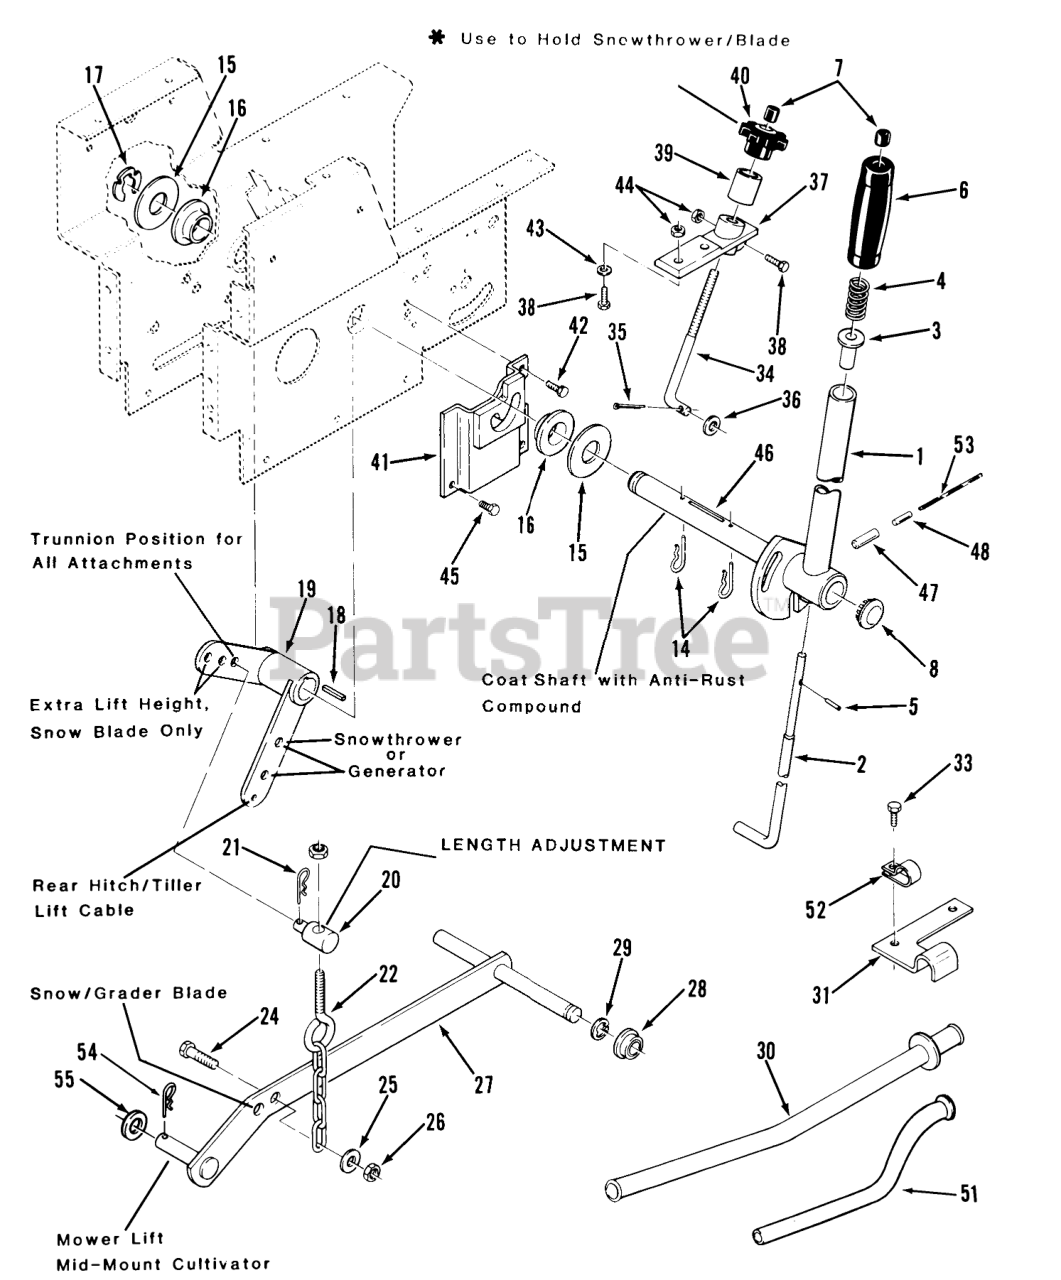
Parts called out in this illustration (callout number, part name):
1	Lift Lever
2	ROD-LATCH LIFT
3	RETAINER-SPRING
4	SPRING-COMPRESSION
5	PIN-SPIROL
6	HANDGRIP
7	CAP-ROD, PLUNGER
8	PLUG
14	Pin-Cotter
15	WASHER
16	BEARING-FLANGE
17	Retainer
18	KEY-SQUARE
19	Bellcrank
20	TRUNNION
21	Hairpin
22	CHAIN-LIFT
24	Bolt
25	WASHER 5/16 SAE
26	Nut
27	ASSY LIFT BAR R
28	BUSHING
29	E Ring
30	TUBE ASSY COMPLET R
31	CLAMP-CONDUIT R
33	BOLT
34	ROD-HEIGHT CONTROL
35	Pop Rivet
36	Washer
37	Casting
38	Bolt
39	Sleeve
40	KNOB-LIFT CONTROL
41	Latch Bracket
42	SCREW
43	WASHER 5/16 SAE
44	Nut
45	Bolt
46	SHAFT-LIFT LEVER
47	SPIROL PIN
48	Roll Pin
51	TUBE-CONDUIT R
52	CLIP
53	Lock Wire
54	Hairpin Cotter
55	Washer
